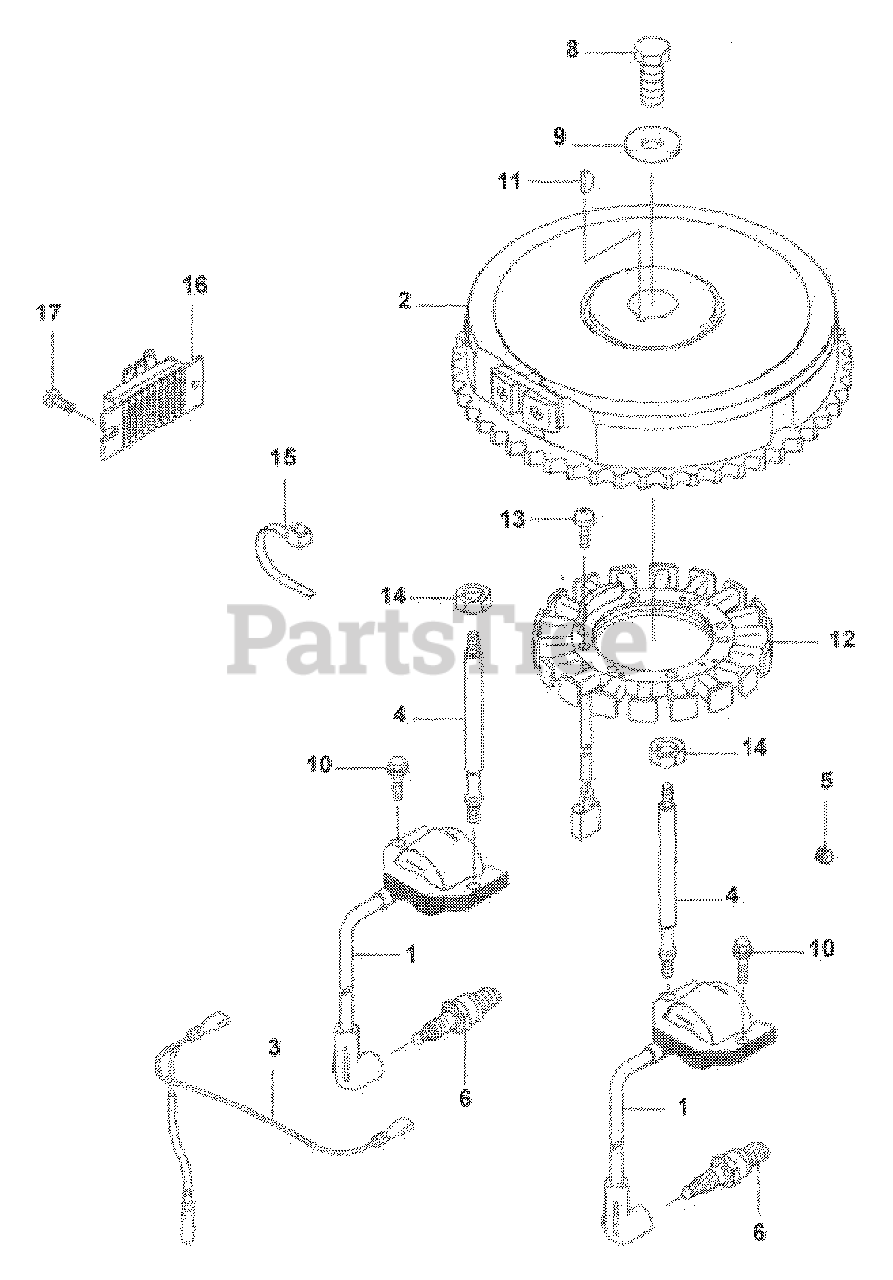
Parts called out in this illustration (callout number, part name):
1	Ignition Coil
4	Stud
6	Spark Plug
8	Bolt 12 x 30
10	Flange Bolt
11	Woodruff Key
12	Stator
13	Pan Screw
14	Hex Nut
15	Tie Strap
16	Voltage Regulator
